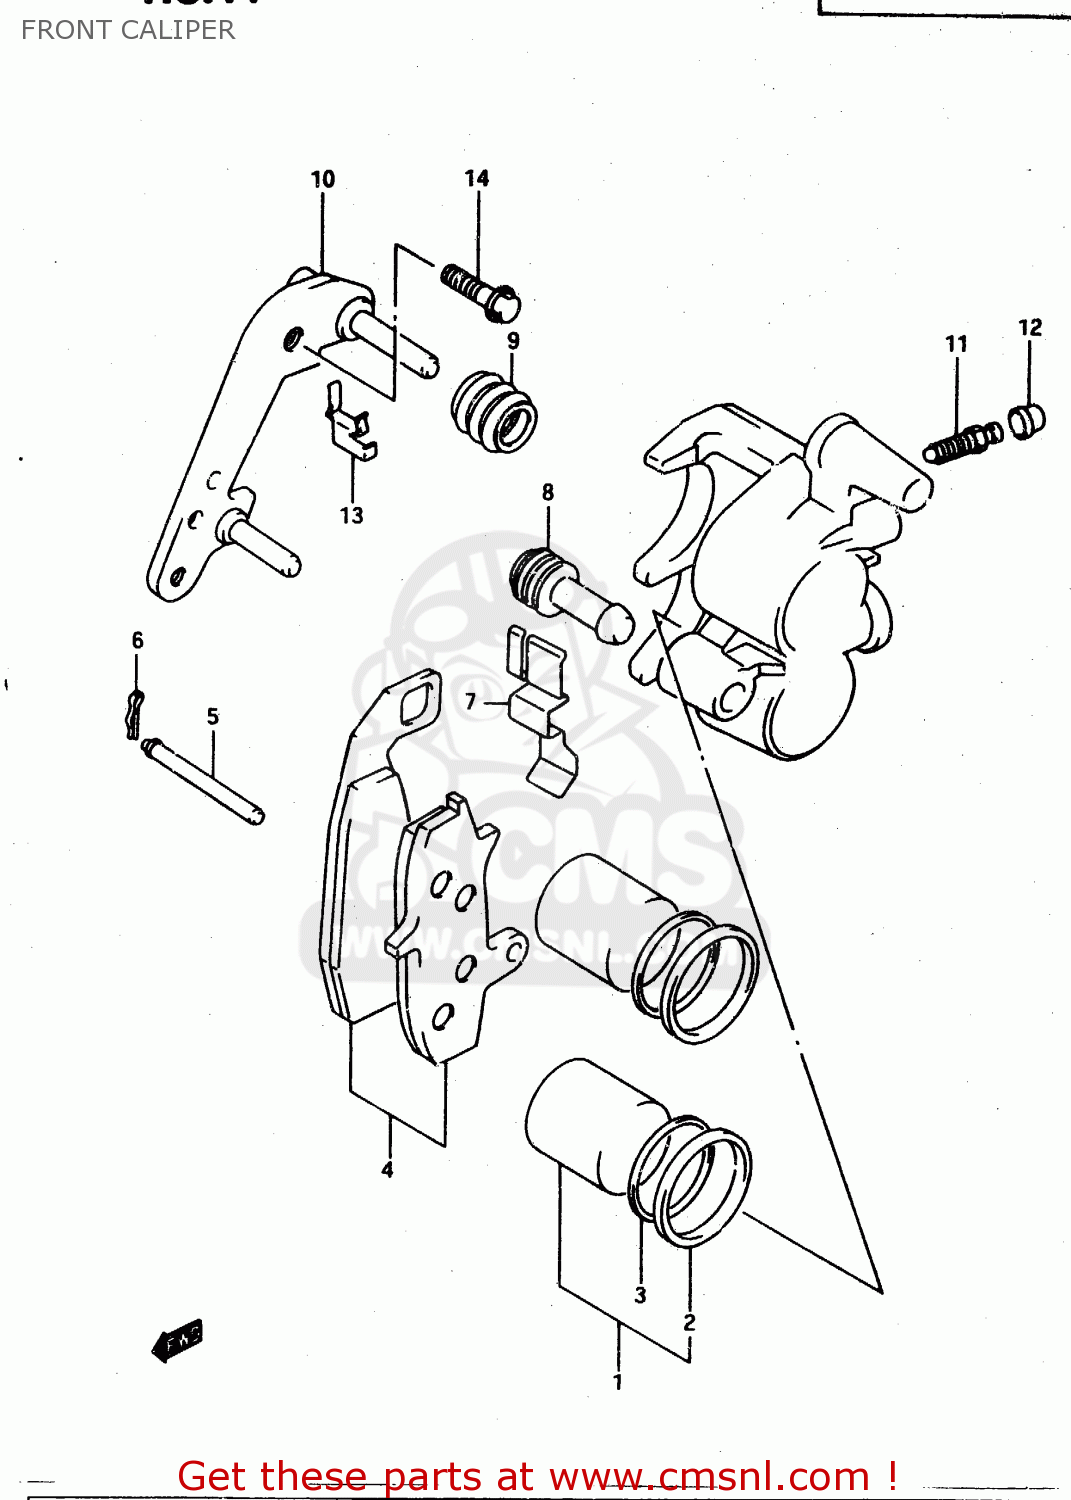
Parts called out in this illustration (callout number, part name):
1	PISTON SET
2	SEAL,PISTON
3	SEAL,WIPER
4	PAD SET (NAS)
5	PIN,PAD
6	CLIP,PAD PIN
7	SPRING,PAD
8	INSULATOR,AXLE
9	BOOT,AXLE
10	BRACKET
11	BLEEDER
12	CAP,BLEEDER PLUG
13	GUIDE,PAD
14	BOLT
